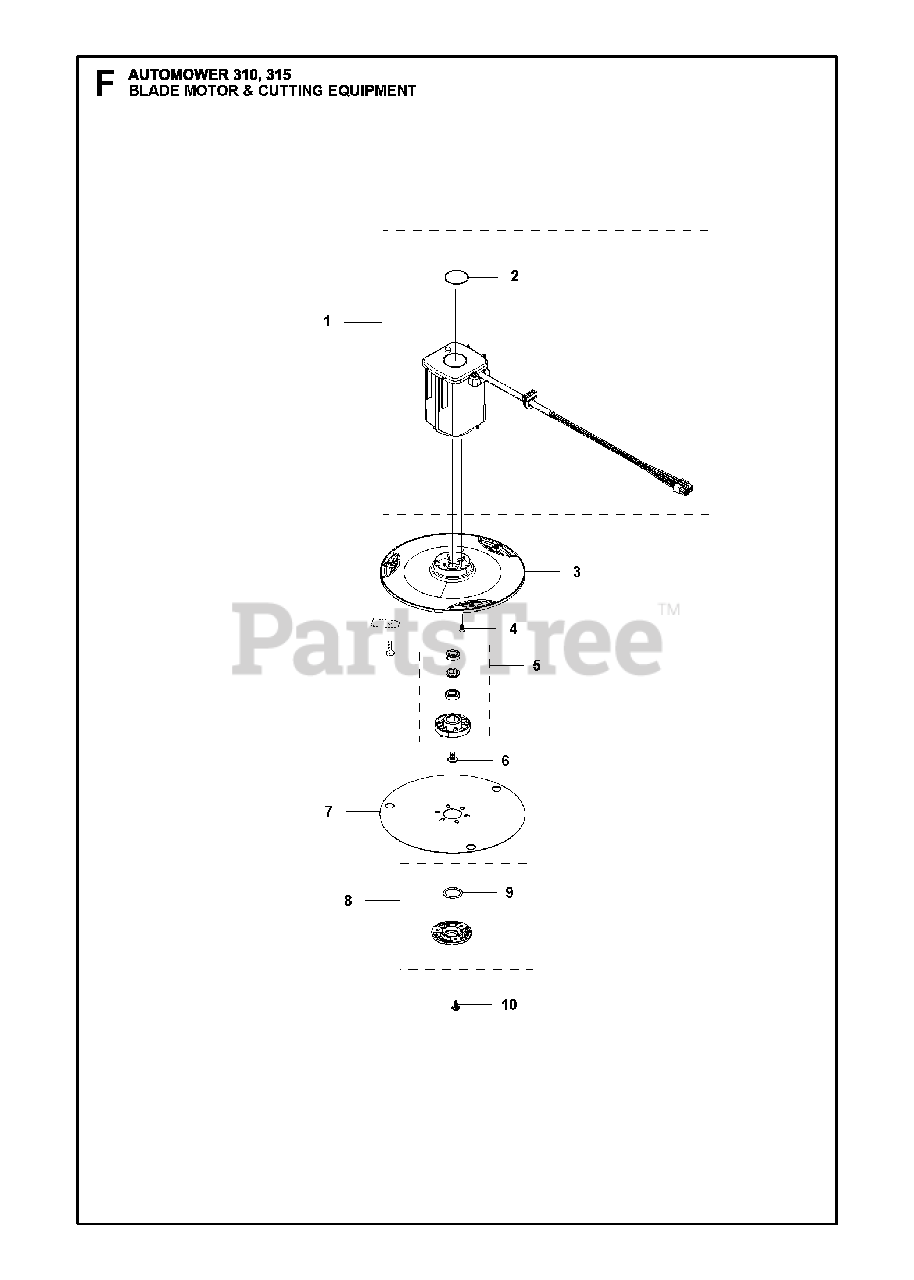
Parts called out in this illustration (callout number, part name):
1	Motor Assembly
2	KIT AIR FILTER KIT 305 - 10 PC
3	CUTTING DISC CUTTING WIDTH 22
4	Torx Screw, M4 X 8 8.8 Nylon Patch
5	BEARING HOUSING ASSY SPARE PAR
6	SCREW
7	SKID PLATE
8	COVER KIT BEARING
9	O-RING 20X2,5 MM
10	SCREW 14MM
